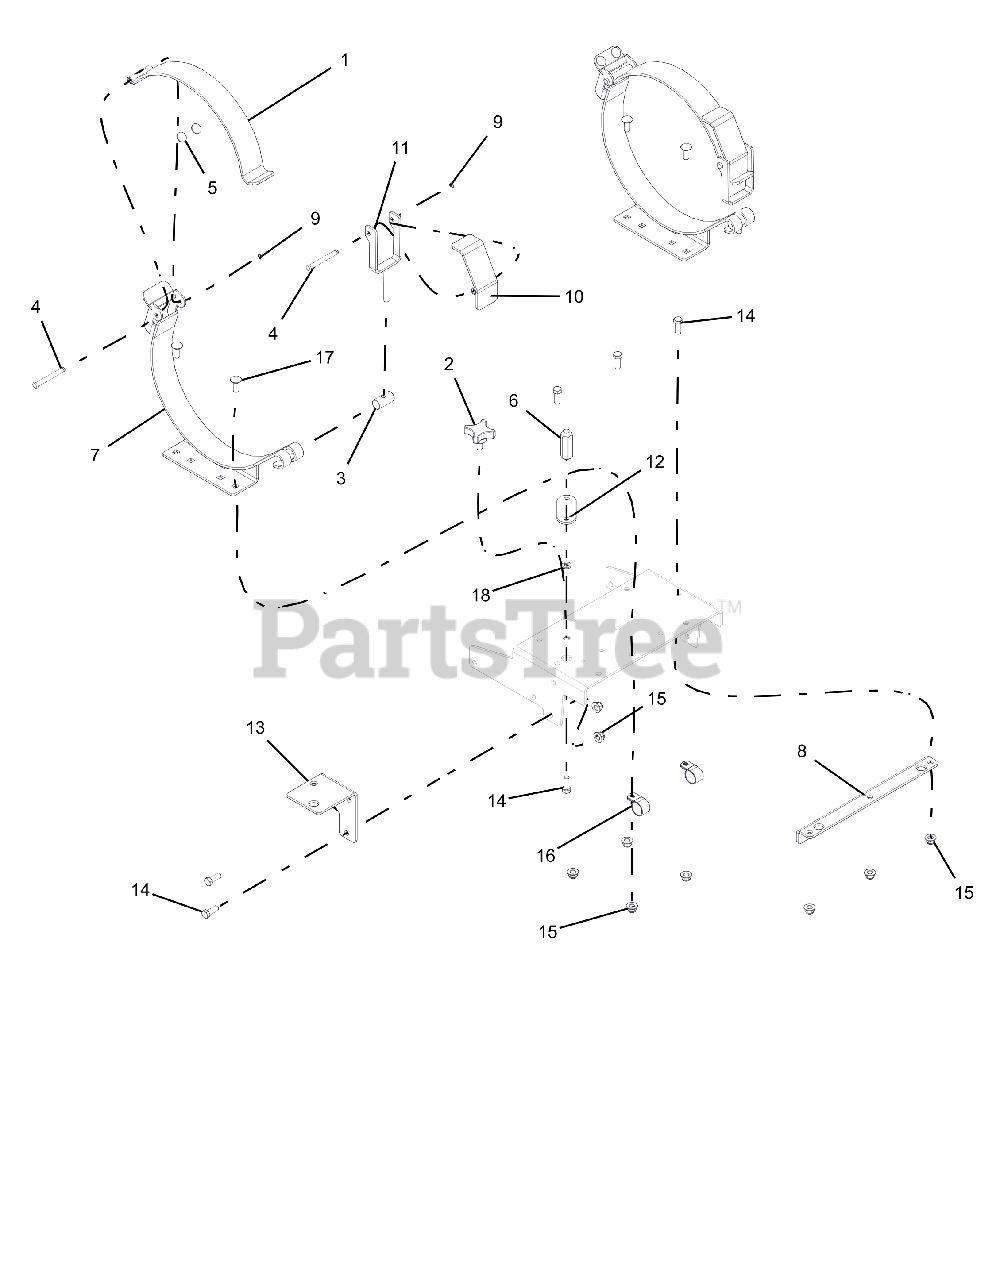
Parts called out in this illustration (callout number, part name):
1	WLDMT, UPPER LP TANK CLAMP
2	KNOB, 3/8-16 x .75
3	PIVOT, LP CLAMP HANDLE
4	PIN, LP CLAMP
5	MAGNET, .75X.060, LP CLAMP
6	POST, INDICATOR LP TANK
7	WLDMT, CLAMP LP TANK
8	STIFFENER, TANK BED
9	RG-RTNG-EXT .312X.025
10	WLDMT, TANK TOGGLE HANDLE
11	WLDMT, TANK CLAMP TOGGLE
12	PLATE, PIN MOUNT
13	BRKT, POST WLDMT
14	BLT-HEX .38-16X1.00 GR5 YWZC
15	NUT-LK-NYL-FLG .38-16 YWZC
16	CLAMP, CUSHIONED STEEL REV
17	BLT-RDHDSQNK .38-16X1.00 G5 YWZC
18	WSHR-LK .38X.094 REG YWZC
